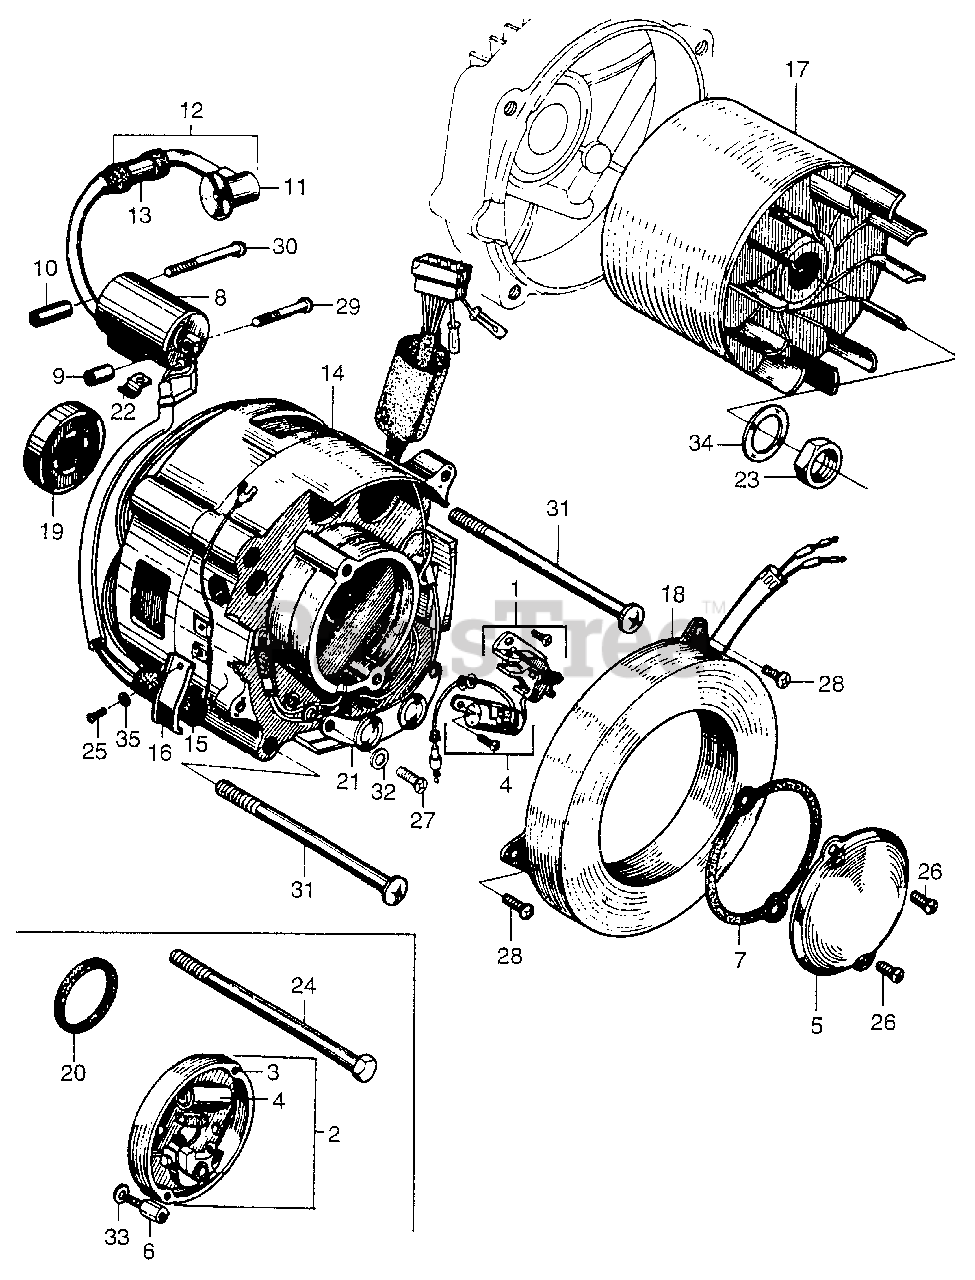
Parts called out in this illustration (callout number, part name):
1	POINTS ASSY.
2	POINTS ASSY.
4	CONDENSER ASSY. (NOT AVAILABLE)
5	COVER, POINTS
7	GASKET, POINTS COVER (NOT AVAILABLE)
8	COIL ASSY., A.C. IGNITION (NOT AVAILABLE)
9	COLLAR A, IGNITION DISTANCE (NOT AVAILABLE)
10	COLLAR B, IGNITION DISTANCE
14	STATOR, ALTERNATOR
15	TUBE A, RUBBER
16	CLAMP, JOINT
17	ROTOR, ALTERNATOR
19	BEARING, RADIAL BALL (6001UU) (SOURCE: VINTAGE PARTS INC.)
21	RECTIFIER, SILICON
23	NUT, SPECIAL (14MM)
25	SCREW, PAN (4X6)
26	SCREW, PAN (4X8)
27	SCREW, PAN (4X20)
28	SCREW, PAN (5X12)
29	SCREW, PAN (5X28)
30	SCREW, PAN (5X40)
31	SCREW, PAN (6X100) (NOT AVAILABLE)
32	WASHER, PLAIN (4MM)
34	WASHER, FLAT (14MM)
35	WASHER, SPRING (4MM)
